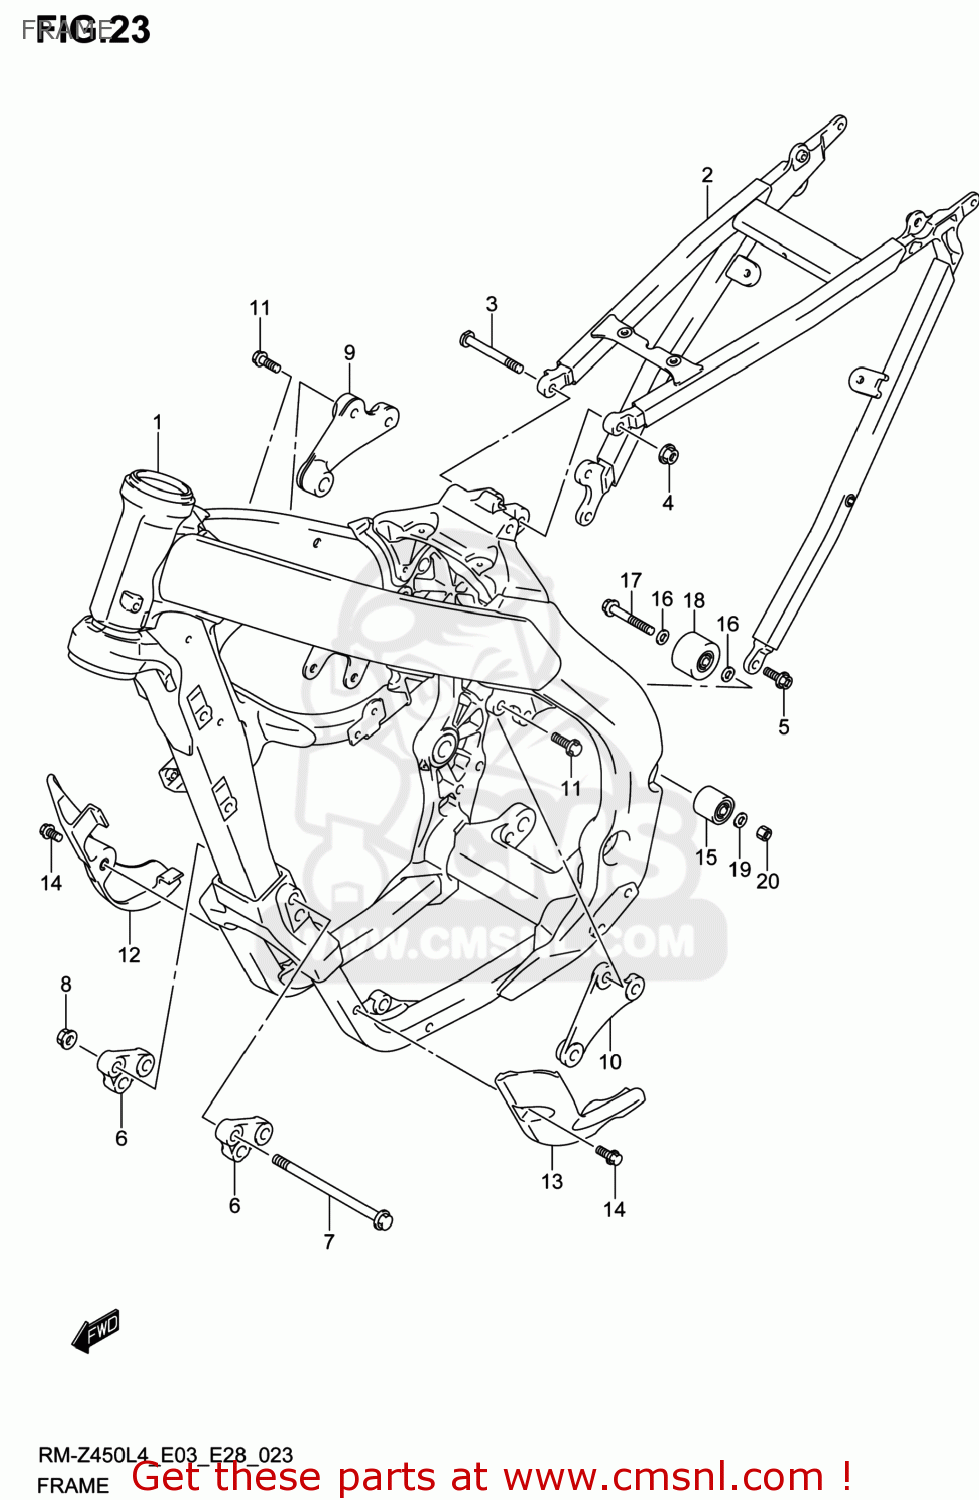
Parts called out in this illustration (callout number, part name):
1	FRAME
2	RAIL,SEAT
3	BOLT,SEAT RAIL UPR
4	NUT
5	BOLT(8X23)
6	BRACKET,ENGINE MOUNTING FR
7	BOLT(10X135)
8	NUT
9	BRACKET,ENGINE MOUNTING UPR,R
10	BRACKET,ENGINE MOUNTING UPR,L
11	BOLT(8X21)
12	PROTECTOR,FR,R
13	PROTECTOR,FR,L
14	BOLT(6X25)
15	ROLLER,CHAIN
16	SHIM(8X16X1)
17	BOLT(8X45)
18	ROLLER,CHAIN
19	SHIM(8X12X1)
20	NUT
